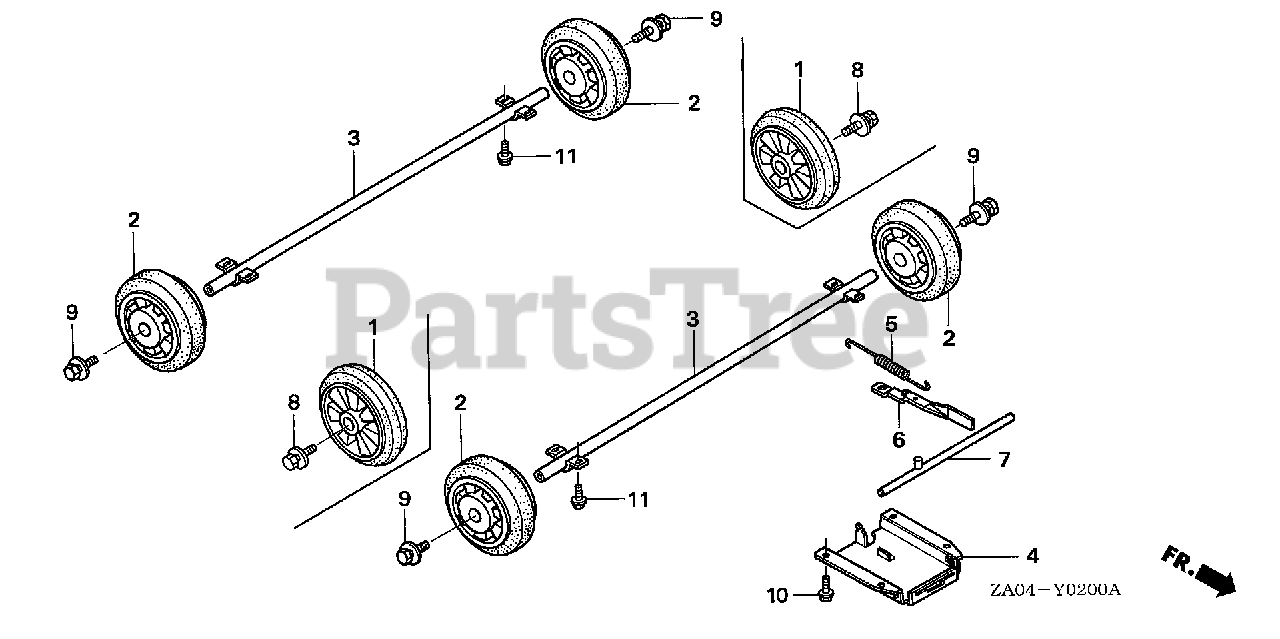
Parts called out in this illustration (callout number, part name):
1	WHEEL
3	SHAFT, WHEEL
4	BASE, WHEEL LOCKING
5	SPRING, WHEEL STOPPER
6	LEVER, WHEEL LOCKING
7	STOPPER, WHEEL
8	BOLT-WASHER (10X16)
10	BOLT, FLANGE (6X10)
11	BOLT, FLANGE (8X14)
